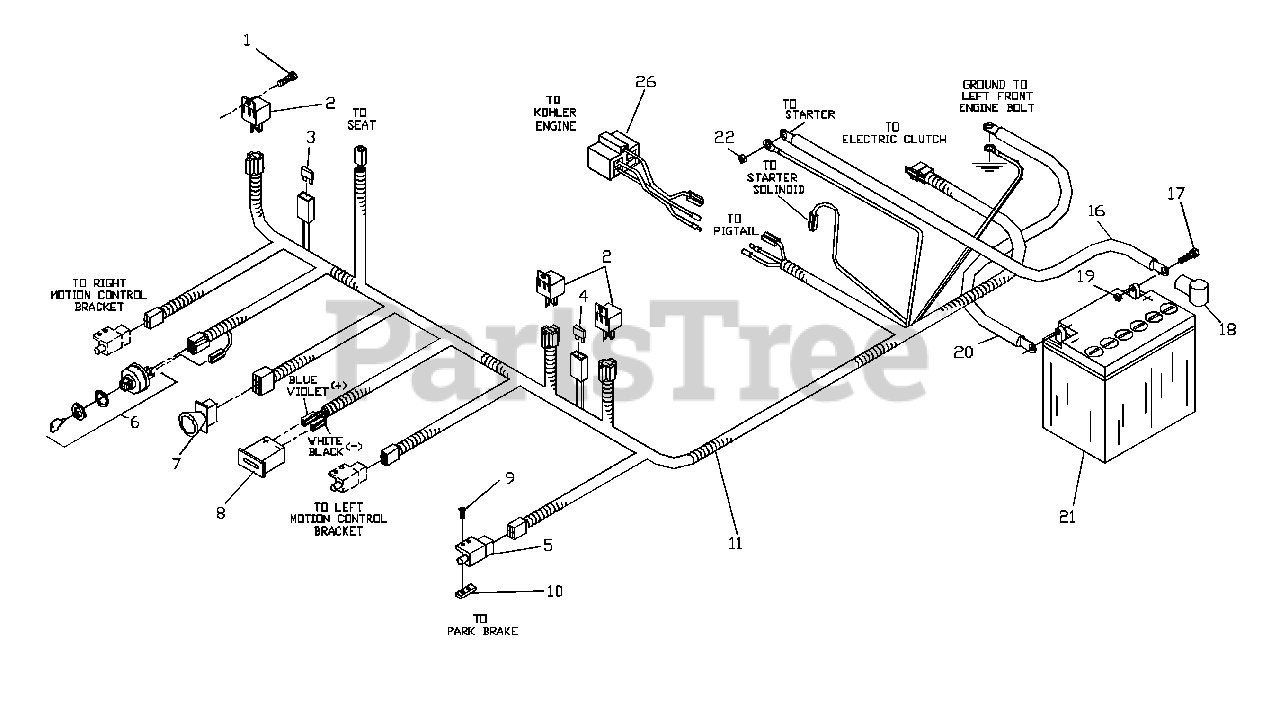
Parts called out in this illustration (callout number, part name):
1	#10 X 1/2 SELF TAPPING
3	7.5 AMP 32 VOLT ATO FUSE
4	20 AMP 32 VOLT ATO FUSE
5	INTERLOCK SWITCH
6	IGNITION SWITCH
7	BLADE SWITCH
8	HOUR METER
9	#10-24 X 5/8
10	TAPPED PLATE
11	WIRING HARNESS
12	NUT 1/4C CENTERLOCK
16	CABLE POSITIVE, LONG
17	HCS 5/16C X 3/4
19	NUT 5/16C CENTERLOCK
20	CABLE NEG.
21	BATTERY
22	NUT 1/4C NYLOC
23	KEY, PADDED
26	PIGTAIL FOR ENG. WIRING
